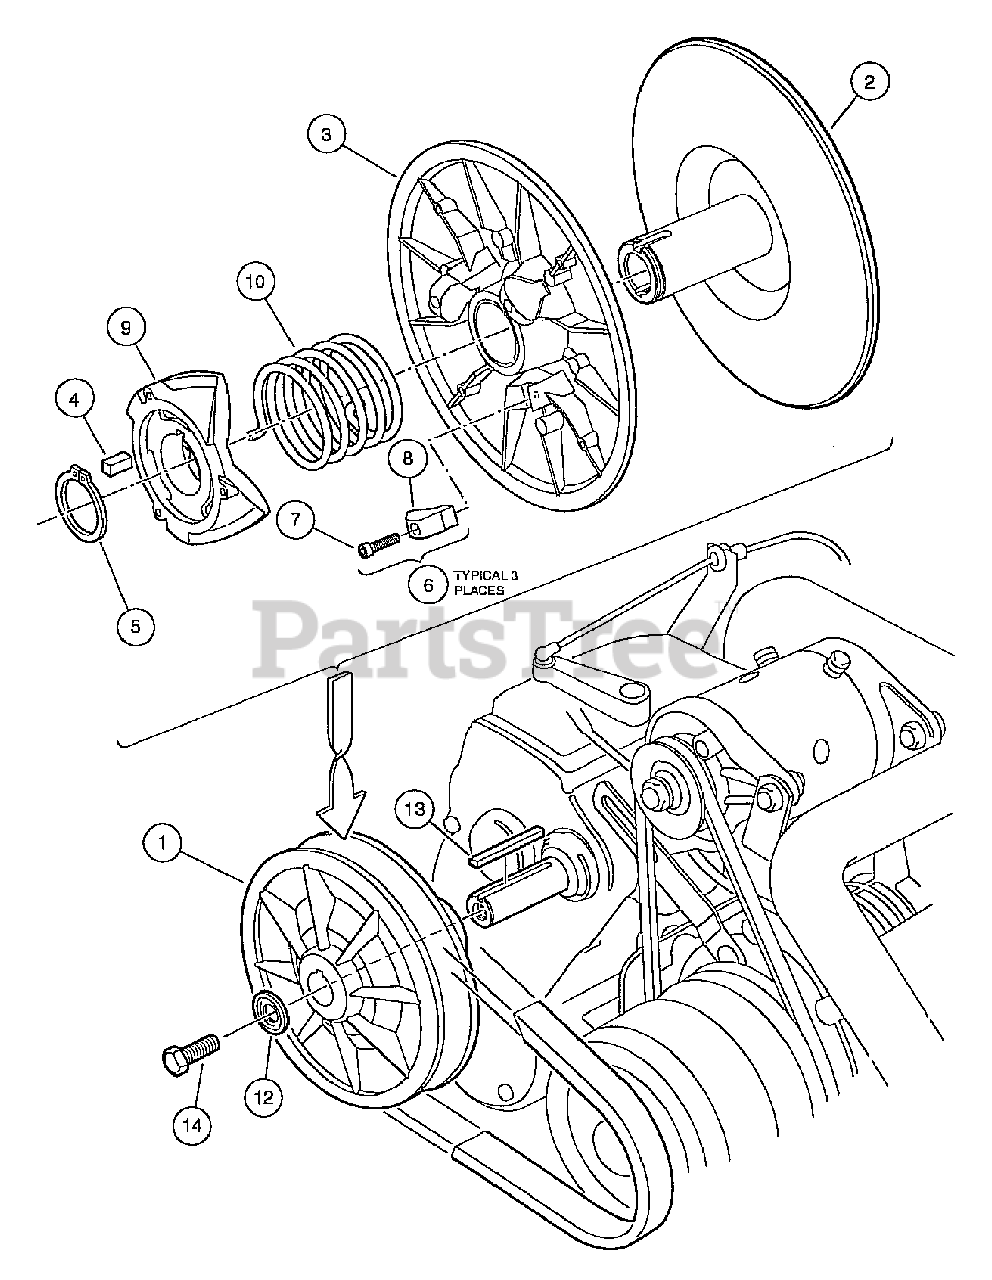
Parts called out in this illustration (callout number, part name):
1	Assembly, Driven Clutch
2	Fixed Face Assy, Driven Clutch
3	Movable-Face Assembly with Bushing
4	Key, Driven Clutch
5	Ring, Retaining
6	Kit, Driven Clutch Button
7	Screw, #8-32 X 3/4 Soc Hd Cap
8	Button, Drive
9	Cam, Driven Clutch
10	Spring, Driven Clutch Reversed
11	Kit, Clutch Repair
12	Washer, Driven Clutch Belleville
13	Key, 3/16 Sq X 1.50"
14	Screw, 5/16-18x3/4 Hx Hd W/ptc
